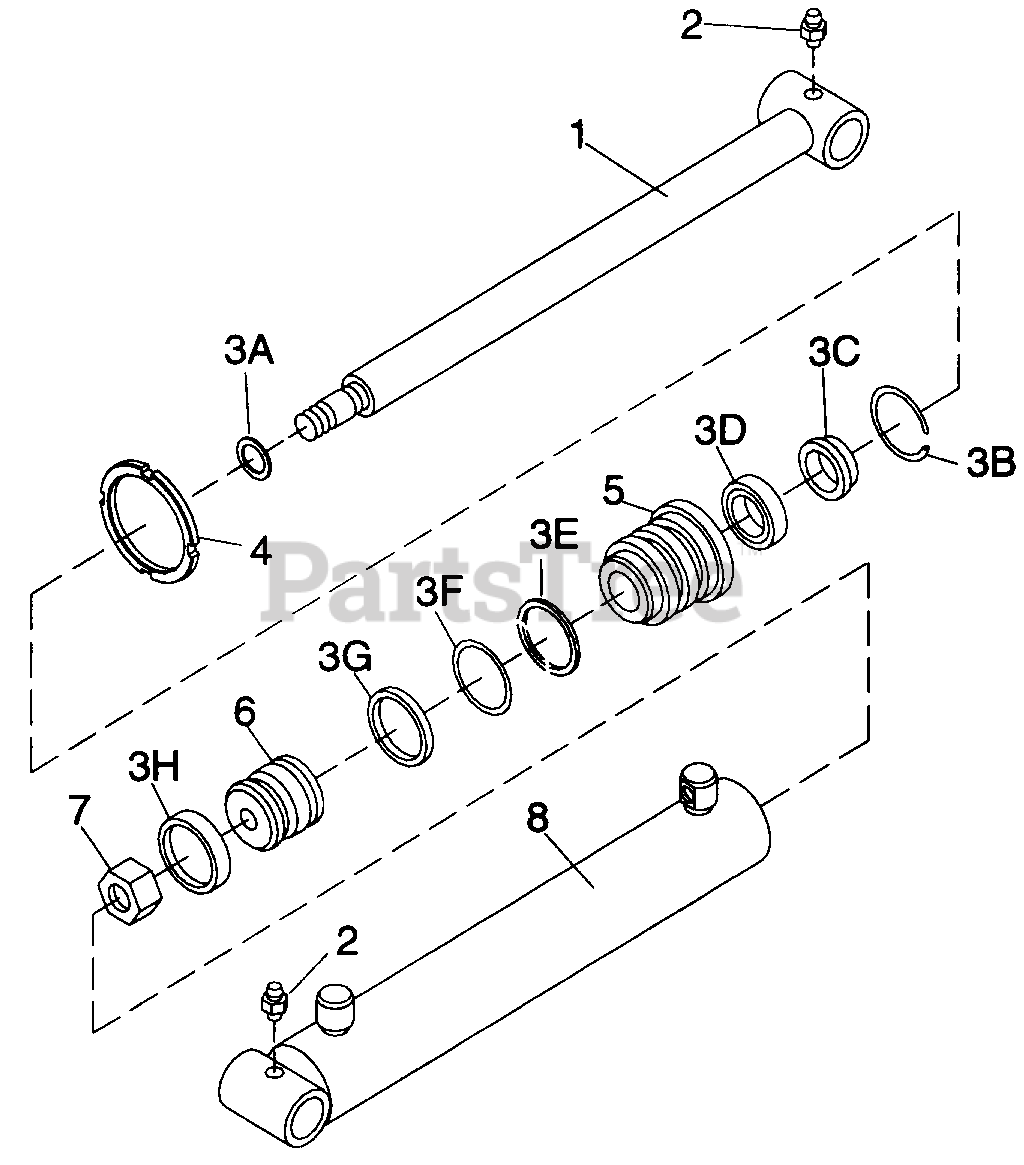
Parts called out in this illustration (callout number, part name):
1	Piston rod
2	Grease fitting
3	Seal kit
3A	3/4 x 7/8 O-Ring
3B	2-1/2 Internal retaining ring
3C	1-1/4 Wiper ring
3D	1-1/4 x 1-5/8 x 5/16 U-Cupseal
3E	2-1/4 x 2-1/2 Backup ring
3F	2-1/4 x 2-1/2 O-Ring
3G	2-1/2 Piston seal
3H	2-1/2 x 1/4 x 1/8 Wear ring
4	1/4 x 2-7/8 Spanner nut
5	2-1/2 OD x 1-1/4 ID Guide
6	2-1/2 OD Piston
7	7/8 NF - 14 Locknut
8	2-1/2 ID Cylinder body
